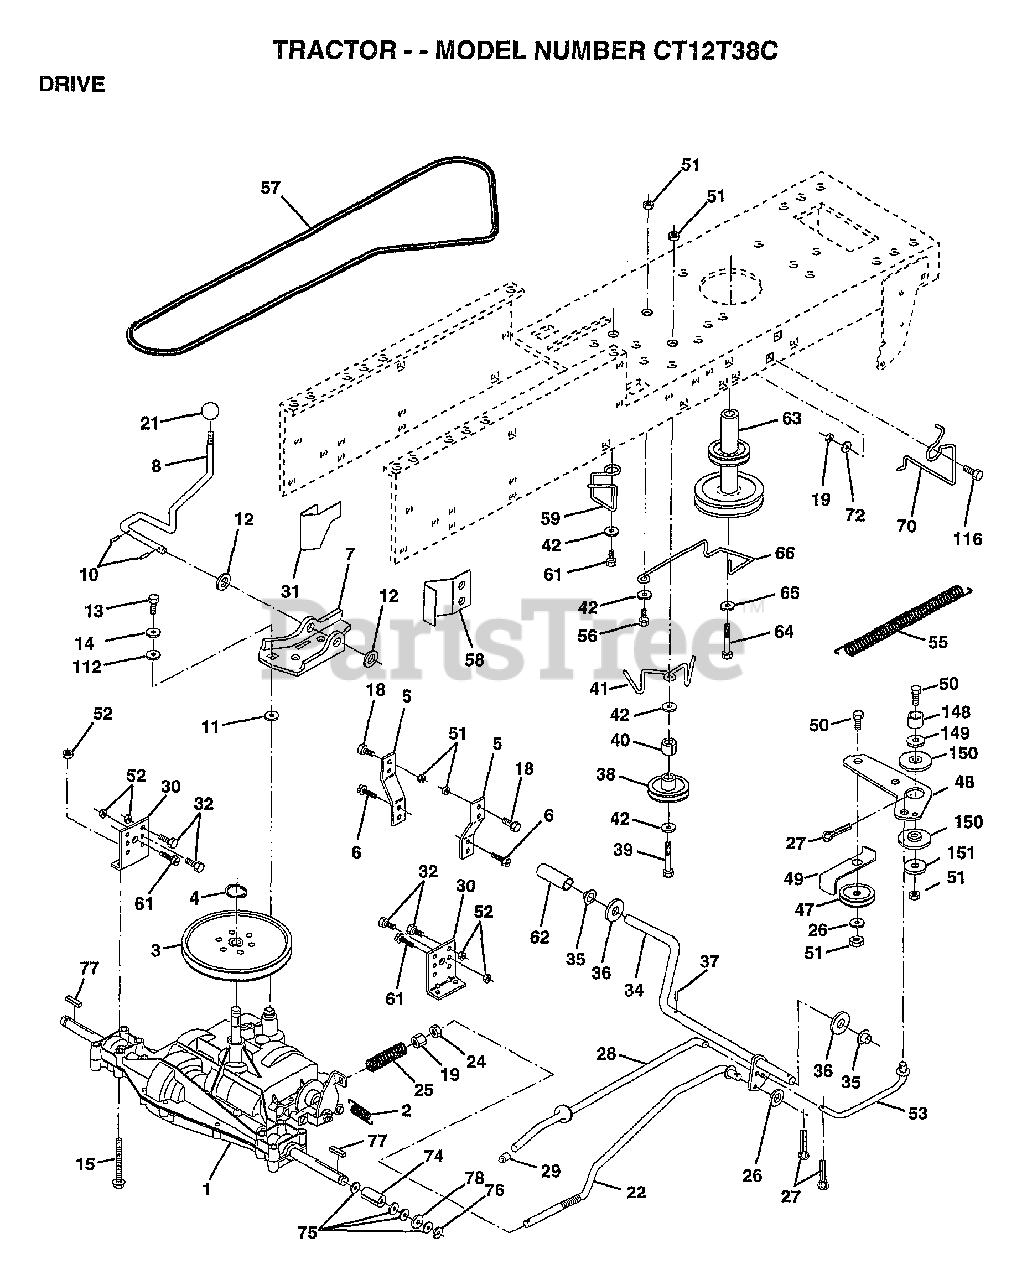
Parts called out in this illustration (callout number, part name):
2	SPRING.BRAKE.RETU
3	PULLEY TRANS
5	STRAP TORQUE
6	SCREW
7	BRKT.SADDLE.SHIFT
8	SHIFT ROD
10	PIN COTTER 1/8
11	WASH-SHFT PLT LT
12	WASHER
13	BOLT.1/4-28.W/PAT
14	LOCKWASHER
15	BOLT.HX.FLG.5/16
18	BOLT
19	NUT
21	KNOB T (1/2-HOLE)
22	BRAKE ROD
24	NUT
25	SPRING ROD LT
26	WASHER
27	COTTER PIN
28	ROD.BRAKE.PARK.LT
29	PLUNGER CAP T
30	TRANSAXLE MTG BKT
31	"KEEPER,BELT LH T"
32	BOLT
34	SHAFT ASM-PEDAL F
35	NYLON BEARING
36	WASHER LT
38	PULLEY.IDLER.FLAT
39	BOLT
40	SPACER T
42	WASHER
48	BELLCRANK.CLUTCH
49	RETAIN BELT
53	"LINK, CLUTCH T"
54	CLIP T
55	"SPRING, RETURN LT"
58	"KEEPER,BELT RH T"
59	KEEPER BELT CNTSP
61	SCREW
62	PEDAL COVER T
63	PULLEY.ENGINE
64	BOLT
65	LOCKWASHER
66	KEEPER-BELT
70	KEEPER BELT ENG
72	WASHER
74	SPACER LT
75	WASHER
76	E-RING LT
77	SQUARE KEY
78	WASHER
112	WASHER LT
116	BOLT RDHD 3/8-16
149	SPACER RETAINER
150	BUSHING.NYLON
151	WASHER
